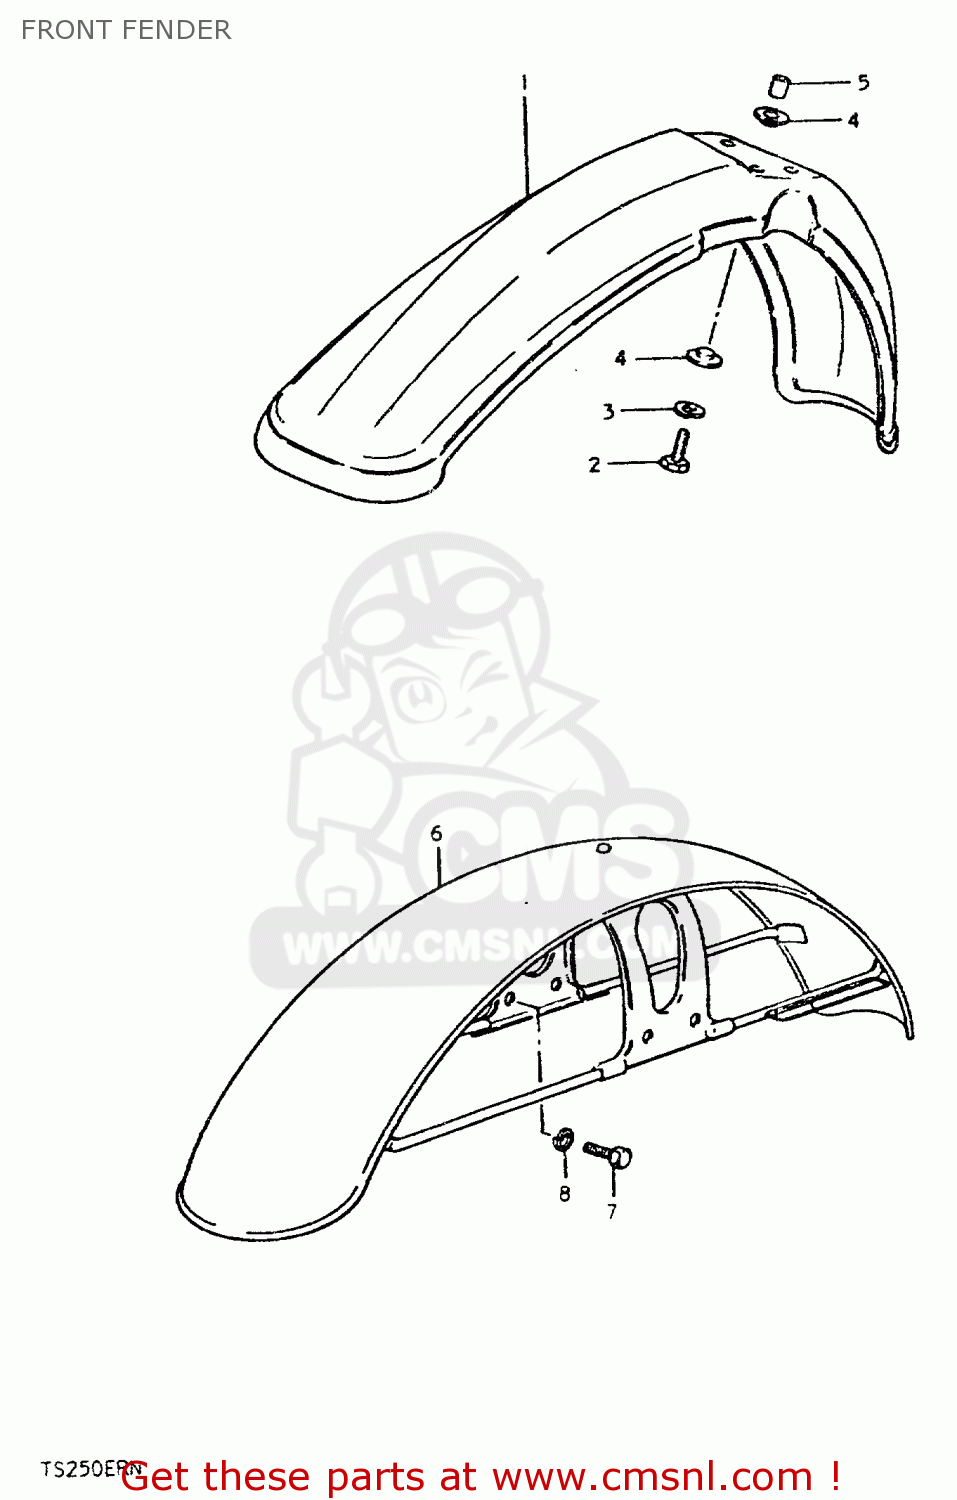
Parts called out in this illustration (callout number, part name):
1	FENDER,FR
2	BOLT
3	LOCK WASHER
4	SPACER
5	SPACER
6	FENDER, FRONT
7	BOLT
8	LOCK WASHER
